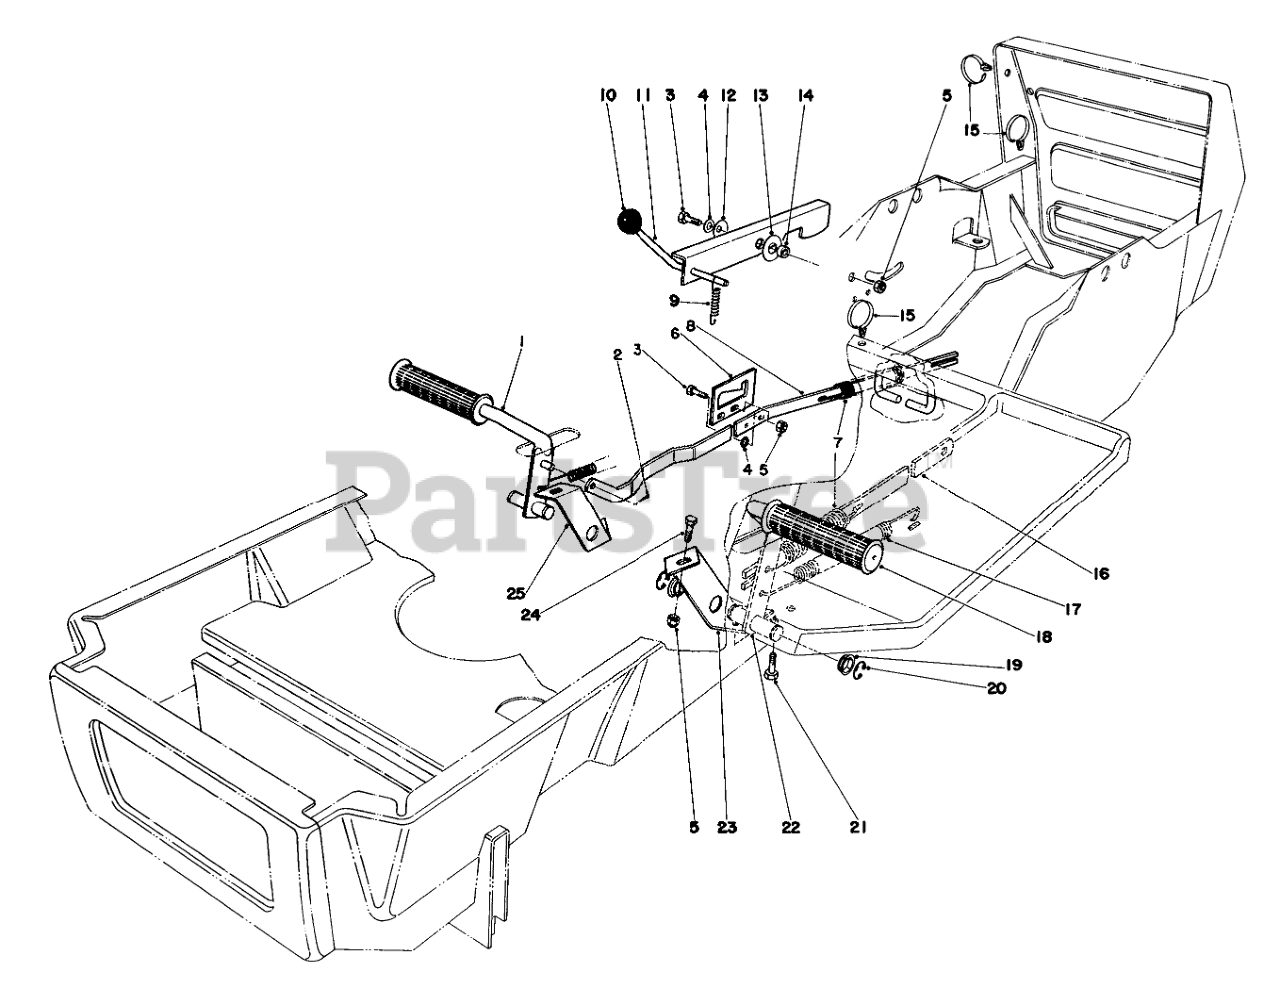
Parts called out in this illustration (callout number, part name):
1	BRAKE PEDAL WA BO
2	PIN-COTTER
3	SCREW-HH
4	WASHER-PLAIN
5	NUT-LOCK, CONE
6	LATCH PLT-BRAKE ROD
7	EXT SPRING O
8	LINK BRAKE ROD WAB
9	CONT ROD SPRING 0
11	PARKING BRAKE WA B
12	WASHER-BELLEVILLE
13	WASHER-PLASTIC
14	SPACER
15	TIE-MOUNT, PUSH
16	CLUTCH ROD LINK B
17	SPRING-EXTENSION
18	Pad-Foot
19	Nyliner
20	E-RING
21	SCREW-HWHTF
22	CLUTCH PEDAL WA BO
23	LH PEDAL SUPT B
24	SCREW-HH
25	RH PEDAL SUPT B
